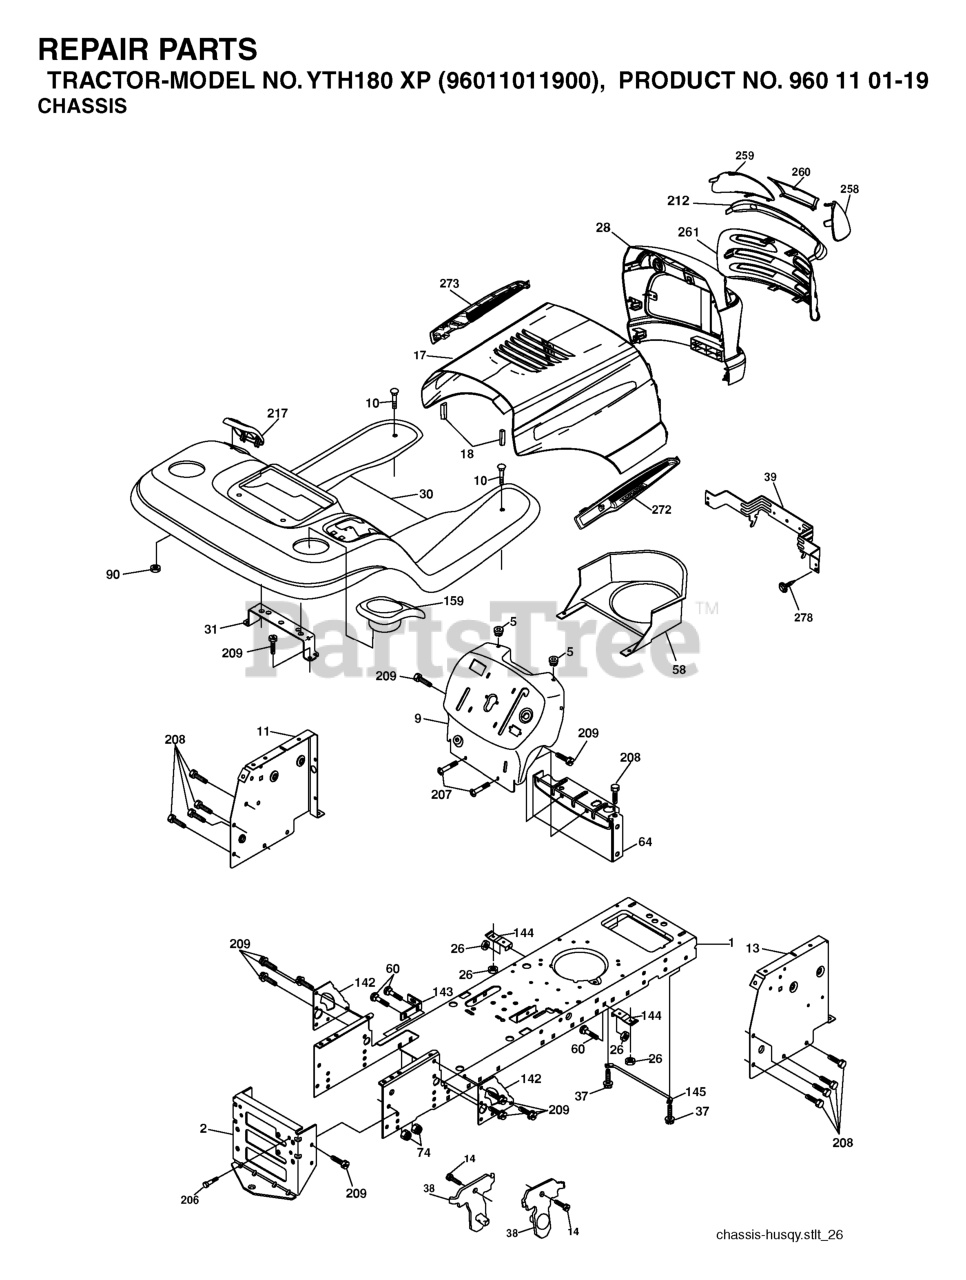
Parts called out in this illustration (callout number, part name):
1	CHASSIS STAMPING
2	DRAWBAR, 12GA
5	BUMPER.RUBBER.HOOD
9	DASH.SLK.STL.PL.M.ELE.N/AM.N/H
10	BOLT D
11	PANEL.DASH.LH.LTX
13	PANEL ASM, DASH RH
17	VENT.HOOD.LASER.III
18	BUMPER.HOOD.LARGE.1.75"
26	NUT
30	FENDER
31	BRACKET.SUPPORT.FENDER
37	Screw 5/16-18 x 1/2 Hex, Self Tapping 5/16-18 x 1/2
38	BRACKET.ASM.PIVOT.MOWER.REAR
39	BRACKET PIVOT LASER
60	Bolt - Rd. Hd. Sq. Neckiage 3/8 16 x 3/4
64	DASH LOWER
90	NUT.PUSH.3/16
142	PLATE REINFORCEMENT
143	BRACKET, SWAYBAR CHASSIS
144	BRKT, FOOT REST
145	ROD PIVOT CHASSIS/HOOD
159	CUPHOLDER
206	SHOULDER BOLT 5/16-18TT
207	SCREW, 5/16-18 X 1/2
208	SCREW 3/8-16X1/2
209	SCREW, 3/8-16X3/4
212	INSERT.LENS.REFLECTIVE
217	CONSOLE FUEL WINDOW
258	LENS LH
259	LENS LH
260	COVER.LENS.HUSQ.LASER
272	VENT.HOOD.LASER.
273	VENT.HOOD.LASER.
278	SCREW
